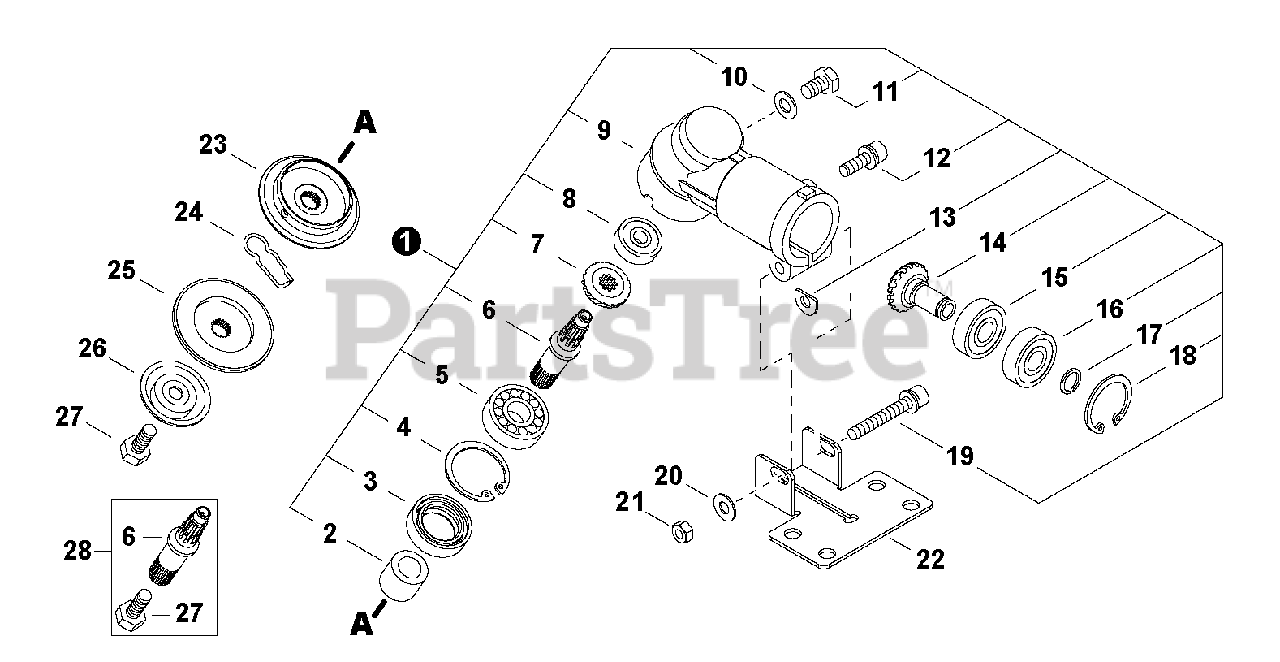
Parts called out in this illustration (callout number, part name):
1	GEAR CASE ASSY
3	SEAL, OIL
4	RING, SNAP Ø32
5	BEARING, BALL 6201
6	SHAFT, GEAR
7	GEAR, BEVEL
8	BEARING, BALL
9	CASE, GEAR
11	BOLT M6×10
12	BOLT M5×16
13	D-WASHER
14	GEAR, PINION
15	BEARING, BALL 6901
16	BEARING, BALL 6901ZZ
17	RING, SNAP Ø12
18	RING, SNAP Ø24
19	BOLT M6×40
20	WASHER 6.5×13×1
21	NUT, HEX M6
22	PLATE, SHIELD MOUNTING
23	PLATE, ADAPTOR - UPPER
24	CLIP, BLADE
25	PLATE, ADAPTOR - LOWER
26	GUARD, BOLT
28	GEAR SHAFT SET
